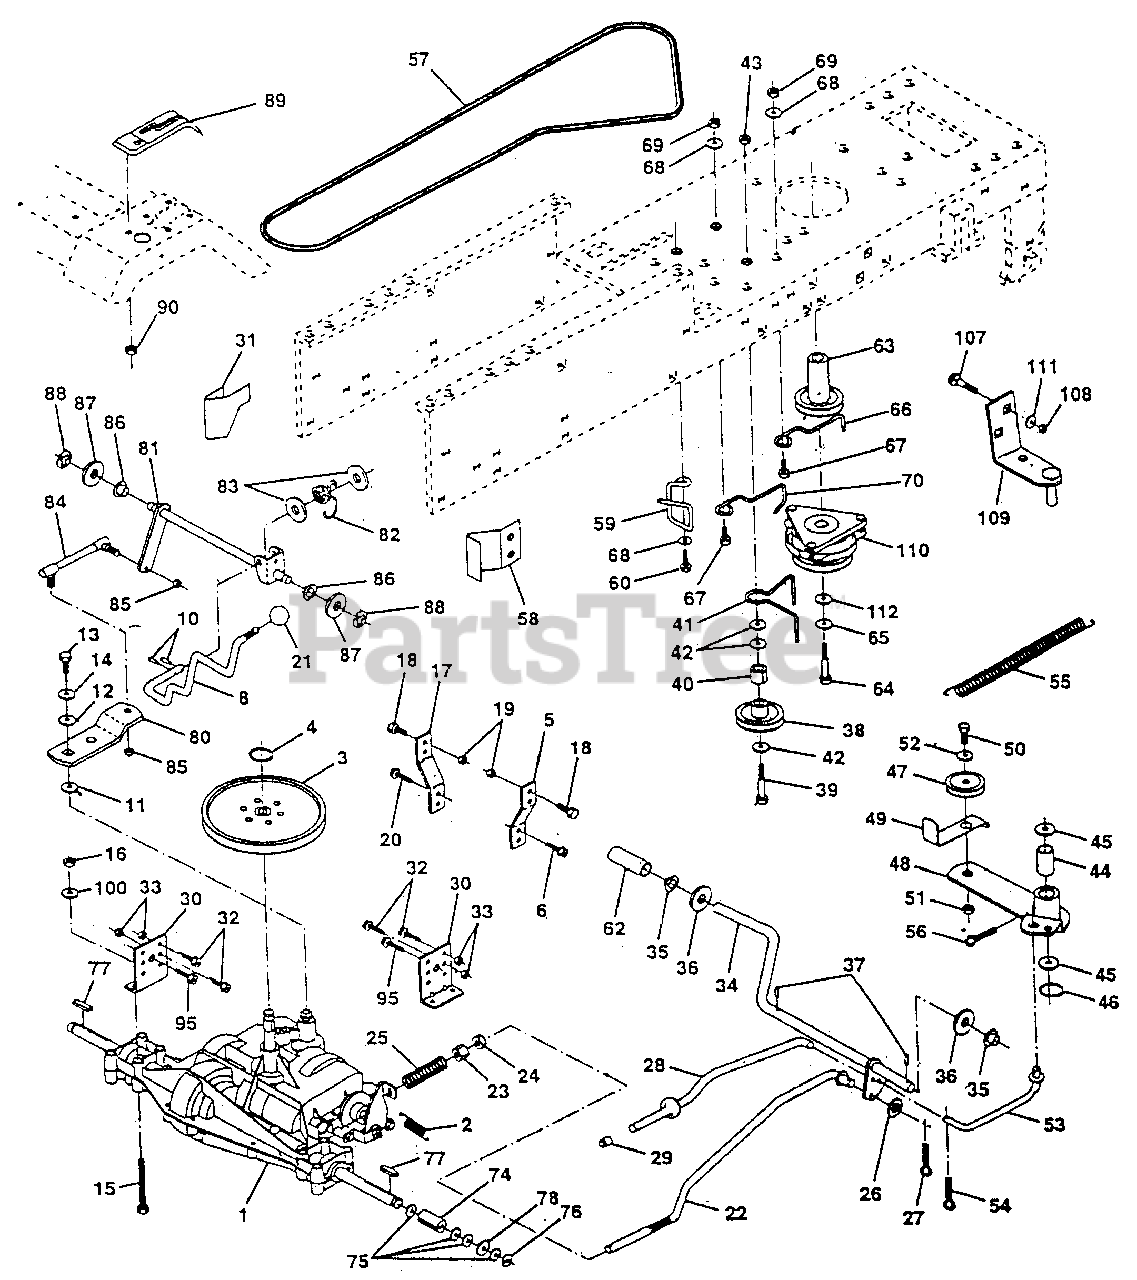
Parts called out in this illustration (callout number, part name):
1	Transaxle 6sp Dana LT Model #4360-81
2	Spring Return Brake T/a Zinc
3	Pulley Transaxle 20" Tires
4	Ring Retainer # 5100-62
5	Strap Torque 30 Degrees
6	Screw Thdrol 5/16-18 X 3/4 TYT
8	Rod Shifter
10	Pin Cotter 1/8 X 1 Cad
11	Washer Plate Sht 388 Sq Hole
12	Washer 15/32 X 3/4 X 16 Ga
13	Bolt Fin Hex 1/4-28unfx3/4 Gr8
14	Washer Lock Hvy Helical 1/4
15	Bolt Fin Hex 5/16-18uncx 2 3/4
16	Nut Lock H w/Insert 5/16-18
17	Strap Torque LT
18	Bolt Fm Hex 3/8-16unc X 1 Gr. 5
19	Nut Lock 3/8-16 Unc
20	Screw Thdrol 5/16-18 X 3/4 TYT
21	Knob Duckhead 3/8-16unc Blk
22	Rod Brake Blk Zinc 27 326
23	Nut Lock Hex W/wsh 3/8-16unc
24	Nut Hex Jam 3/8-16 Unc
25	Spring Rod Brake 2 00 Zinc
26	Washer 13/32 X 13/16 X 16 Ga
27	Pin Cotter 1/8 X 3/4 Cad
28	Rod Brake Parking 14 500
29	Cap Brake Parking Black
30	Bracket Mtg Transaxle
31	Keeper Belt LH LT 14 Ga
32	Bolt Hex Hd 5/16-18unc X 3/4
33	Nut Lock 5/16-18
34	Shaft Asm Pedal Foot 1 930
35	Bearing Nylon Blk 629 Id
36	Washer 21/32 X 1 X 16 Ga
37	Pin Roll 3/16 X 1'
38	Pulley Idler Flat
39	Bolt Fin Hex 3/8-16unc X 2-3/4
40	Spacer Split 395 X 59 Bzp
41	Keeper Belt Retainer
42	Washer 13/32 X 13/16 X 12 Ga
43	Nut Lock 3/8-16 Unc
44	Bearing Nyl 503 X 628 X 1 25
45	Washer Hardened
46	Ring Klip #t5304-50
47	Pulley Idler V Groove Plastic
48	Bellcrank Asm Clutch
49	Retainer Belt Style Spring
50	Bolt Hex Hd 3/8-16unc X 1-1/2
51	Nut Crownlock 3/8-16 Unc
52	Washer 13/32 X 13/16 X 16 Ga
53	Link Clutch 7 66
54	Pin Cotter, 1/8 X 3/4 Cad
55	Spring Return Clutch 6 75
56	Pin Cotter 1/8 X 3/4 Cad
57	V-Belt Ground Drive 95 25 42"
58	Keeper Belt RH LT Pnt/zinc 16g
59	Keeper Belt Chassis Span Ctr
60	Screw Thdrol 3/8-16x3/4 Ty-tt
62	Cover Pedal Premuim
63	Engine Pulley LT/YT
64	Bolt, Hex 7/16-20 x 4-1/4
65	Washer Lock Hvy Hlcl Spr 7/16
66	Keeper Belt Engine LH LT
67	Bolt Fin Hex 3/8-16 unc X 1
68	Washer 13/32 X 13/16 X 12 Ga
69	Nut Crownlock 3/8-16 Unc
70	Keeper Belt Engine BZP Zinc
74	Spacer Split
75	Washer 25/32 X 1 1/4 X 16 Ga
76	E-ring #5133-75
77	Key Square 2 0 X 1845/ 1865
78	Washer 25/32 X 1-5/8 X 16 Ga
80	Arm Shift Transaxle
81	Shaft Asm Cross 20"t 42" deck
82	Spring Torsion T/a
83	Washer 17/32 3/4 X 16 Ga
84	Rod Tie Shift Adj Ball
85	Nut Nylock 1/4-28
86	Bushing Rod Strg 629/632 Id
87	Washer 21/32 X 1-1/4 X 16 Ga
88	Ring Klip #5304-62
89	Console Shift 6sp W/ign LT
90	Nut Self-thd wsh-hd 1/4 zinc
95	Screw Thdrol 3/8-16 x 3/4
100	Washer 11/32 x 3/4 x 16 Ga.
107	Bolt, Carriage 5/16-18 x 3/4
108	Nut Crownlock 5/16 - 18
109	Bracket Asm. Clutch
110	Clutch Electric
111	Washer 11/32 x 5/8 x 12 Ga.
112	Washer 1-1/2 OD X 15/32 ID X .250
